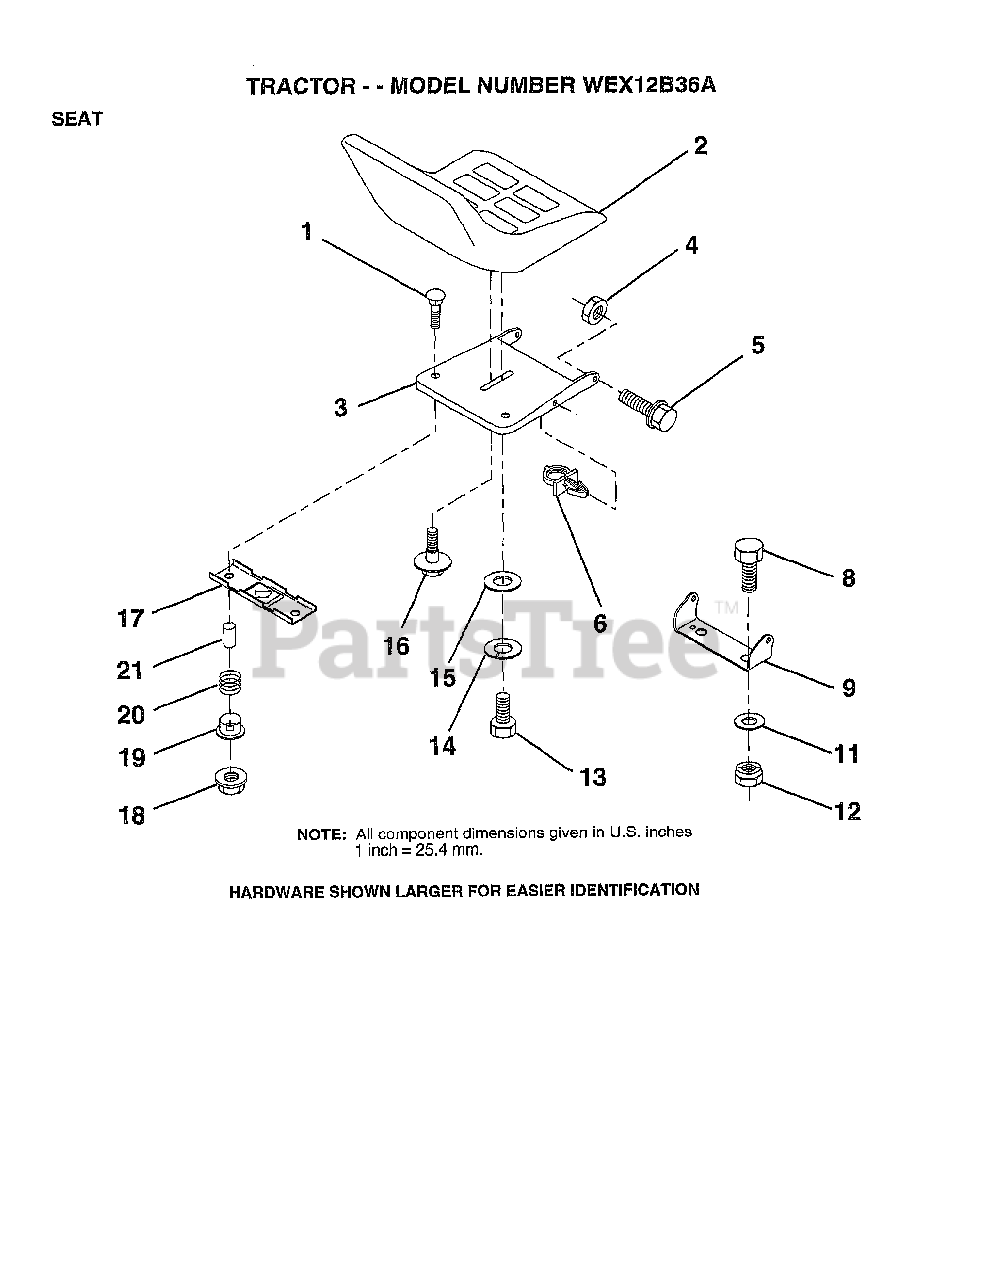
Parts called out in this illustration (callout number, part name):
1	BOLT-RD HD SQ NK
3	PAN-SEAT
4	NUT
5	"BOLT,SHOULDER"
6	CLIP.PUSH-IN.HING
8	BOLT
9	BRACKET PVT SEAT
11	WASHER
12	NUT
13	BOLT
14	LOCKWASHER
15	WASHER
16	"BOLT,SHOULDER"
17	BRKT SWITCH
19	BUSHING
20	SPRING
21	SPLIT SPACER
